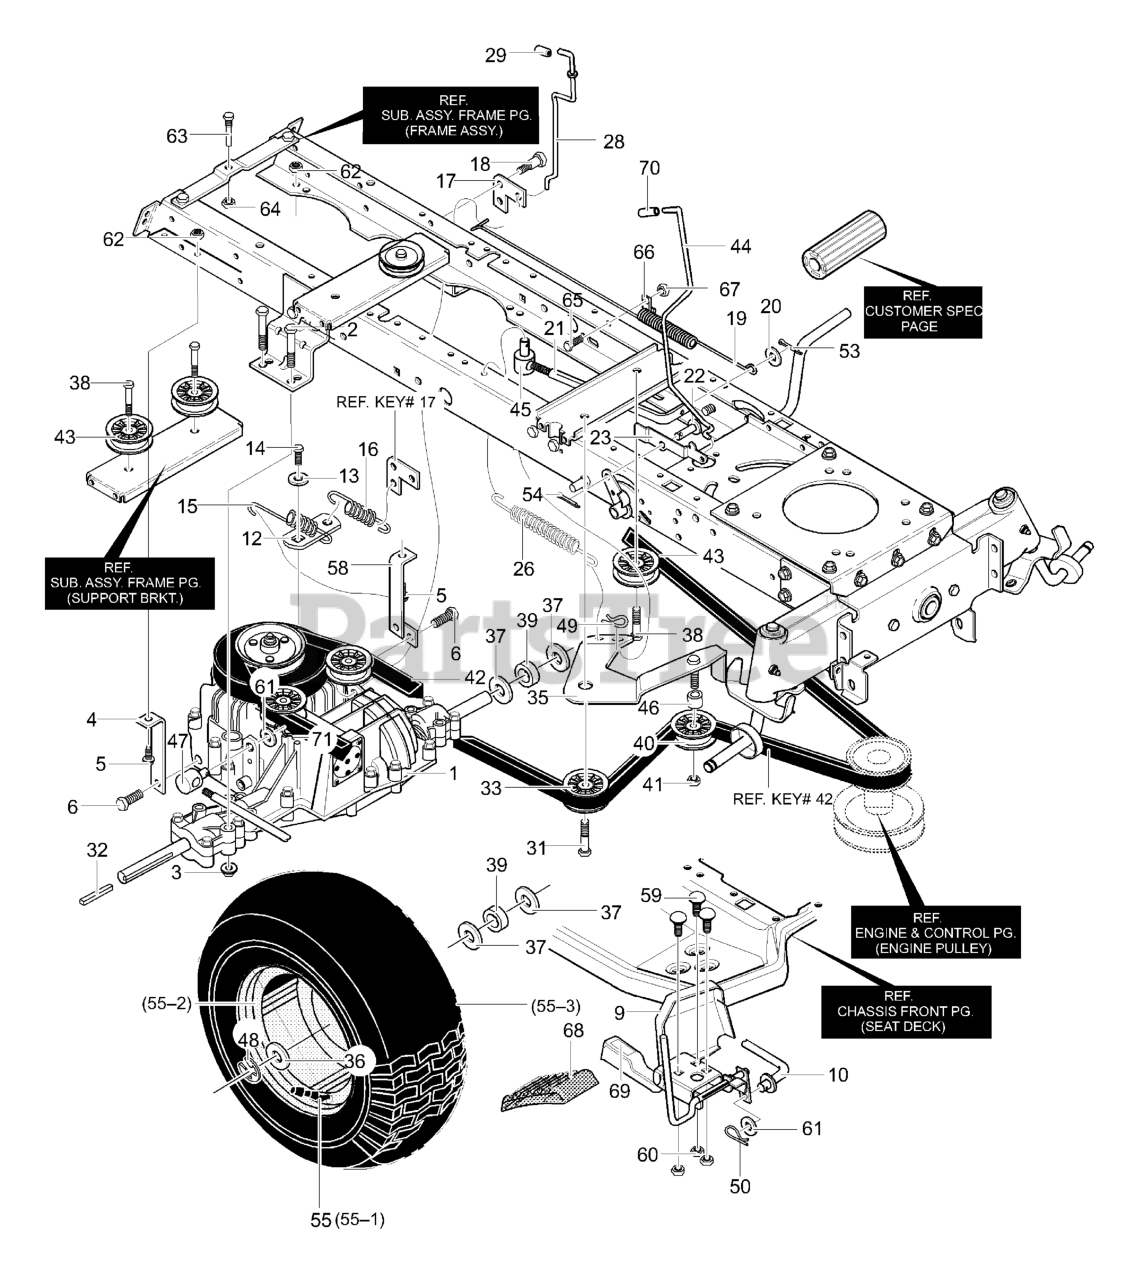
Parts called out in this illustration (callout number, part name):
1	Transaxle, MST205 **
2	Screw, 5/16-18 x 2.50
3	Nut, 5/16-18
4	Bracket, Stabilizer Hydro
5	SCREW, 5/16-18 x 1.00
6	Screw, 5/16-18 x .75
9	Pedal Assy. Hydro
10	Rod, Foot Control
12	Bracket, Shift
13	Washer, Transaxle
14	Screw, 1/4-28x.750
15	Spring - Transaxle
17	Bracket, Disconnect Lever
18	Bolt, 5/16-18 HHSH
19	Spring, Brake
20	Washer, Flat
21	Rod, Clutch
22	Pin, Clevis
23	Latch, Park Brake
26	Spring, Tension
28	Rod, Disconnect
29	Grip, Hydro Disconnect
31	Screw, 3/8-16 x 1.25
32	Key, Square
33	Pulley, Idler
35	Assy, Idler Arm Traction
36	Washer, Flat
37	Washer, Flat
38	Screw, 3/8-16 x 1.25
40	Pulley, Idler
41	Nut, 3/8-16
42	Belt, V 4L 112.75
43	Pulley, Idler
44	Park Brake control Rod
45	Nut, 5/16-18 Adjusting
46	Spacer, 1/2 to 17mm
47	Adjusting Nut, 1/2-13
48	E-Ring
49	Pin, Hair
50	Pin, Hair
53	Pin, Cotter
54	Pin, Cotter
55	Tire & Rim
55-1	Valve Stem
58	Asm., Weld Bracket, Stabilizer
59	Bolt, Carriage 5/16-18x.75
60	Nut, 5/16-18 Hexwdfllk Whiz
61	Flatwasher, .515x.88x.0
62	Nut, 5/16-18 Hexwdfllk
63	Screw Guide
64	Nut, 5/16-18 Hexwdfllk Whiz
65	Screw, 1/4-20x.50
66	Retainer, Wire
67	Nut, 1/4-20 Wdflwhiz-Lk
68	Pedal, Pad Sandpaper
69	Pad, Toe Sandpaper
70	Cap, Dump Valve Rod
71	Hair Pin
